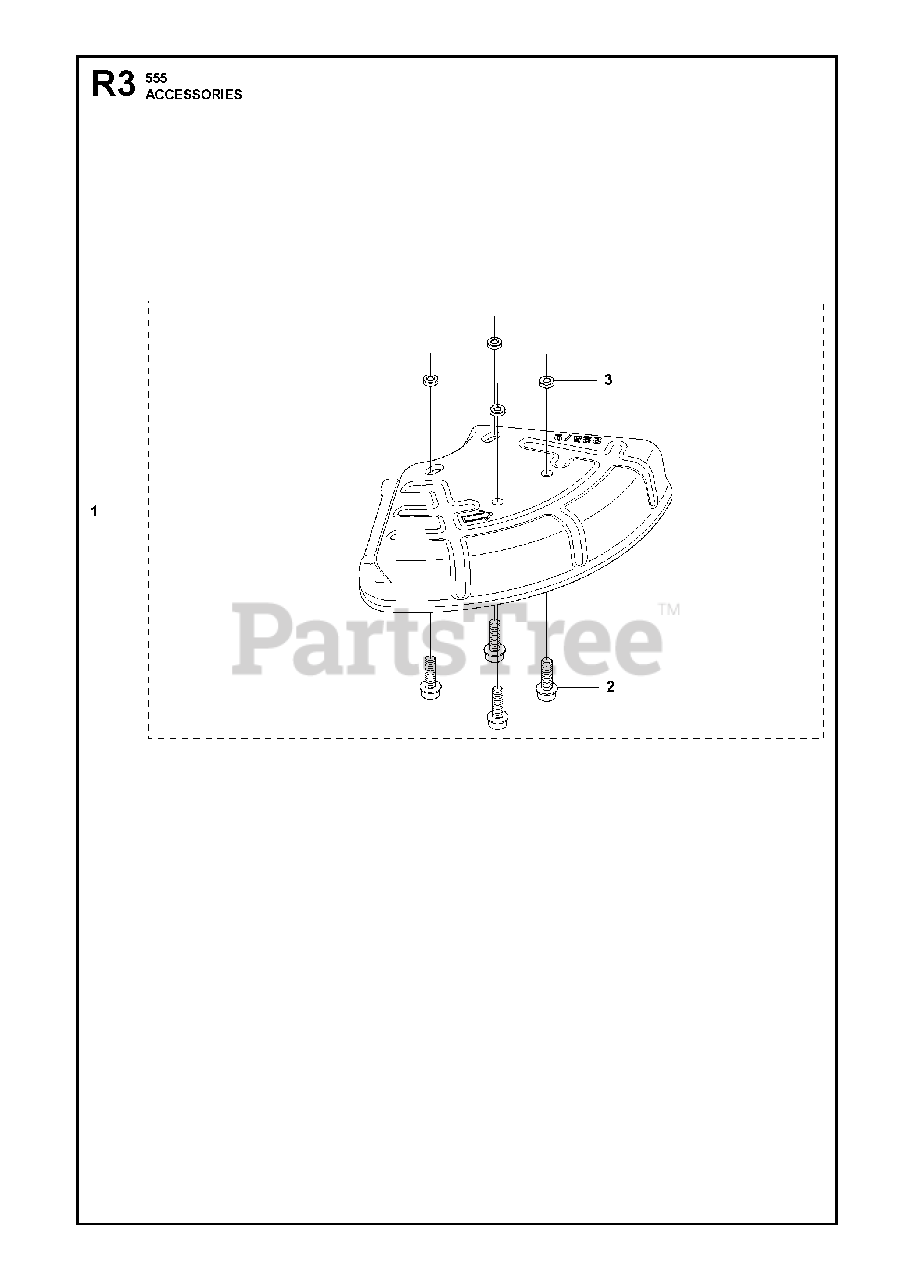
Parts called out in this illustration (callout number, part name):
1	BLADE GUARD
2	SCREW
3	LOCKING NUT
